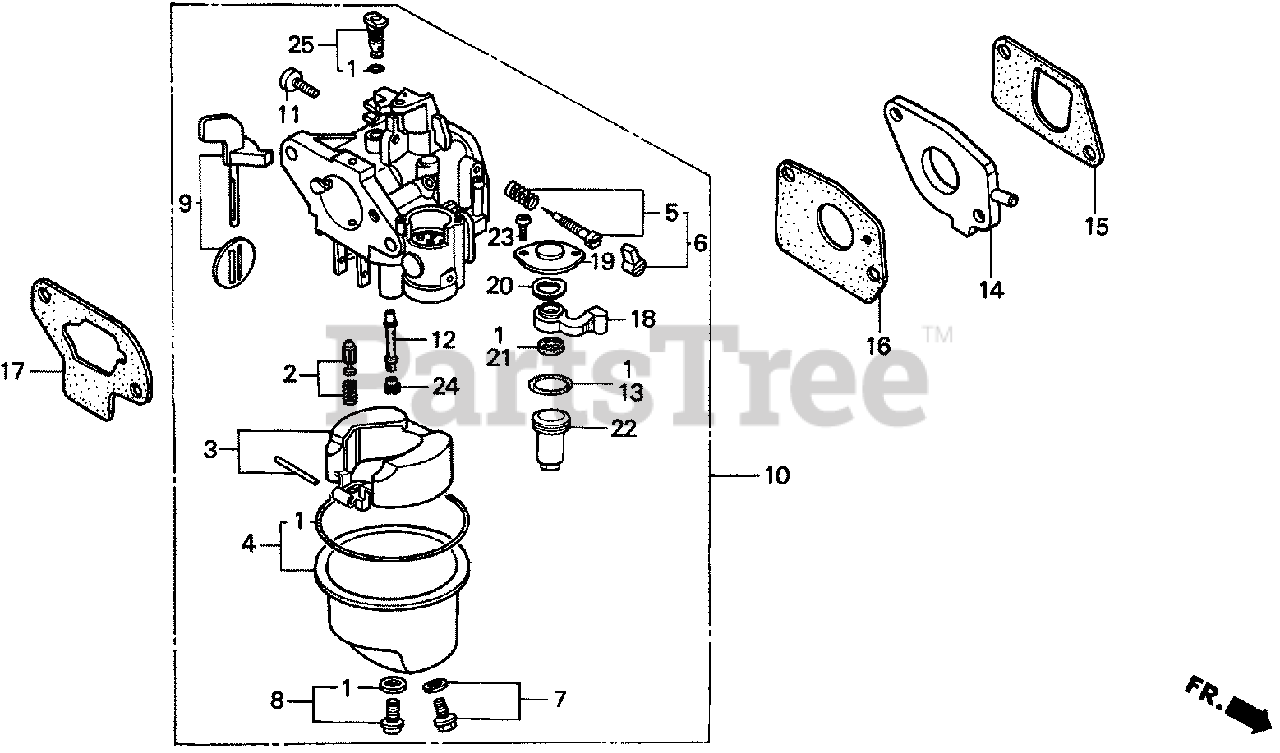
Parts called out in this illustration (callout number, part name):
1	GASKET SET
2	VALVE SET, FLOAT
3	FLOAT SET
4	CHAMBER SET, FLOAT
5	SCREW SET, PILOT
7	SCREW SET, DRAIN
8	SCREW SET
9	CHOKE SET
10	CARBURETOR ASSY. (BF11C C)
11	SCREW, THROTTLE STOP
12	NOZZLE, MAIN
13	O-RING
14	INSULATOR, CARBURETOR
15	GASKET, INSULATOR
16	GASKET, CARBURETOR
17	GASKET, AIR CLEANER
18	LEVER, VALVE
19	PLATE, LEVER SETTING
20	SPRING, VALVE LEVER
21	GASKET, VALVE
22	CUP, FUEL STRAINER
23	SCREW, PAN (3X6)
24	JET, MAIN (#58)
24	JET, MAIN (#52)
24	JET, MAIN (#55)
25	JET SET, PILOT (#38)
25	JET SET, PILOT (#40)
